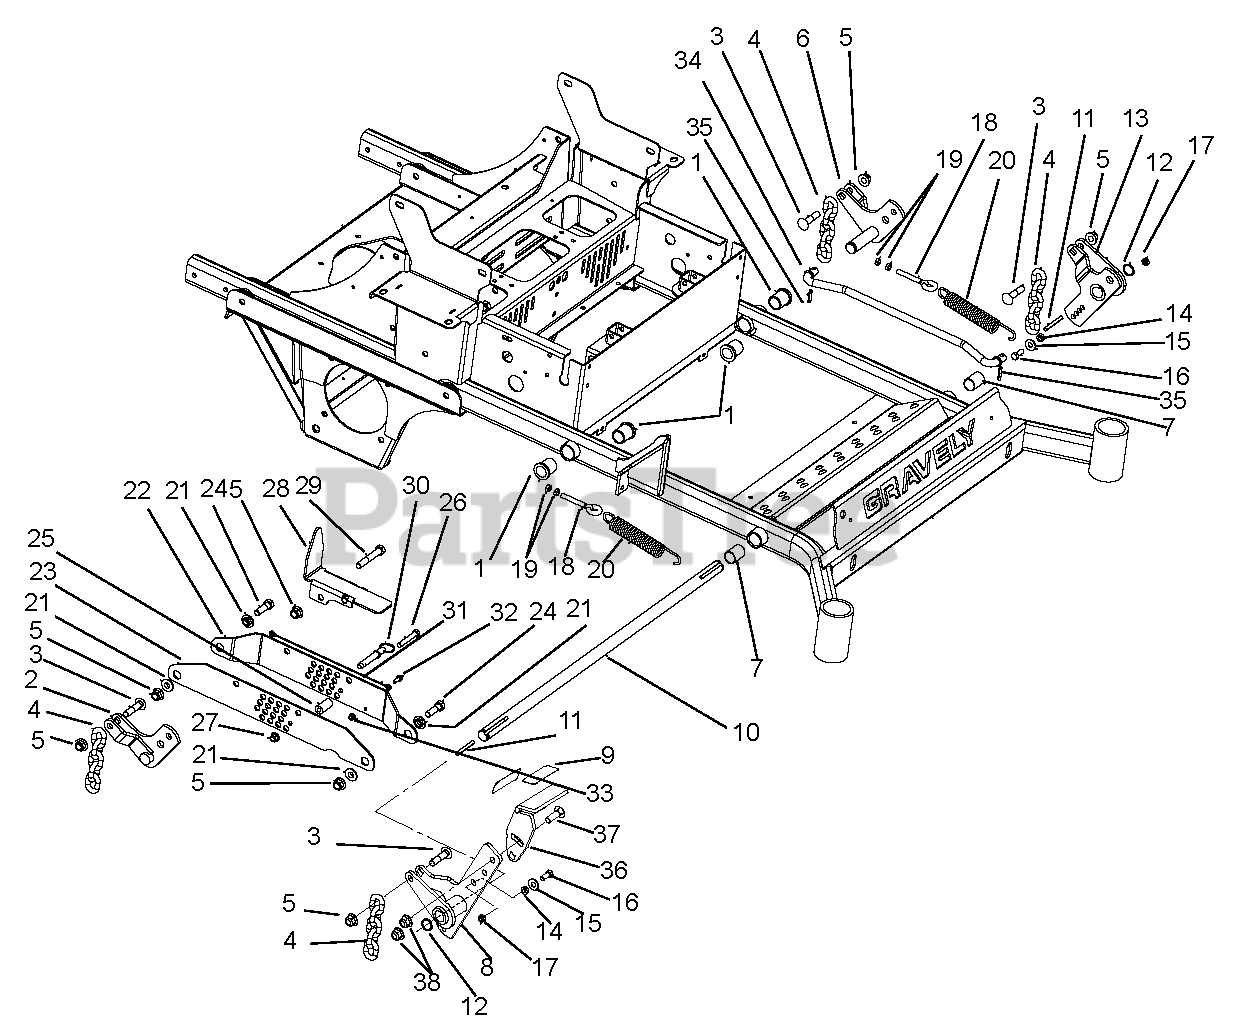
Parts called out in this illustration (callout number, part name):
1	Bushing, Flange 1.00 x 1.25 x 1.50 x 1.50
2	Weldment, Rear Deck Lift Right Hand
3	Bolt, Round Head Square Neck .50-13 x 2.25 G5YZ
4	Chain, 5 Link 3/8 Mower Lift
5	Nut, Locking Nyloc Flange .50-13
6	Weldment, Rear Deck Lift Left Hand
7	Bushing,1.00 ID x 1.125 OD x 1.50 LG
8	Weldment, Deck Foot Lift
9	Grip Pedal 1.50 x 3.00
10	Shaft, Front Mower Lift
11	Key, Square .25 x 2.50 x .25 SAE
12	Ring, Retaining External 1.00 x .078
13	Weldment, Front Deck Lift Left Hand
14	Bushing, Sleave .377 x .624 x .235
15	Washer, Flat Steel .438 x 1.00 x .083
16	Bolt, Hex .38-16 x 1.00 Grade 5
17	Nut, Locking Center Jam .375-16
18	Bolt, Eye .375-16 x 2.50
19	Nut, Hex Jam .375-16
20	Spring, Tension .162 x 1.25 x 8.25 WLD 25
21	Bushing, Flange .515 x .750 x .395 x 1.120
22	Bracket, Lift/Cut Height Inboard Right Hand
23	Bracket, Lift/Cut Height Outboard Right Hand
24	Bolt, Hex .50-13 x 1.75 Grade 5
25	Spacer, .375 x .750 x 1.54
26	Bolt, Hex .38-16 x 2.50 Grade 5
27	Nut, Locking Nyloc Flange .38-16
28	Weldment, Mechnical Lock-Up
29	Bolt, Hex .50-13 x 3.25 Grade 5
30	Pin, .50 x 2.00
31	Cable, 12.0 Lanyard, Nylon
32	Bolt, Hex .25-20 x .75 Grade 5
33	Nut, Locking Nyloc Flange .25-20
34	Rod, Lift Assist 19.35"
35	Pin, Roll .250 x 1.25 Stainless Steel
36	Adjustable Foot Lift Pedal, Black
37	Bolt, Round Head Square Neck .50 x 13 x 1.50 Grade 5 YZ
38	Nut, Locking Nyloc Flange .50-13
